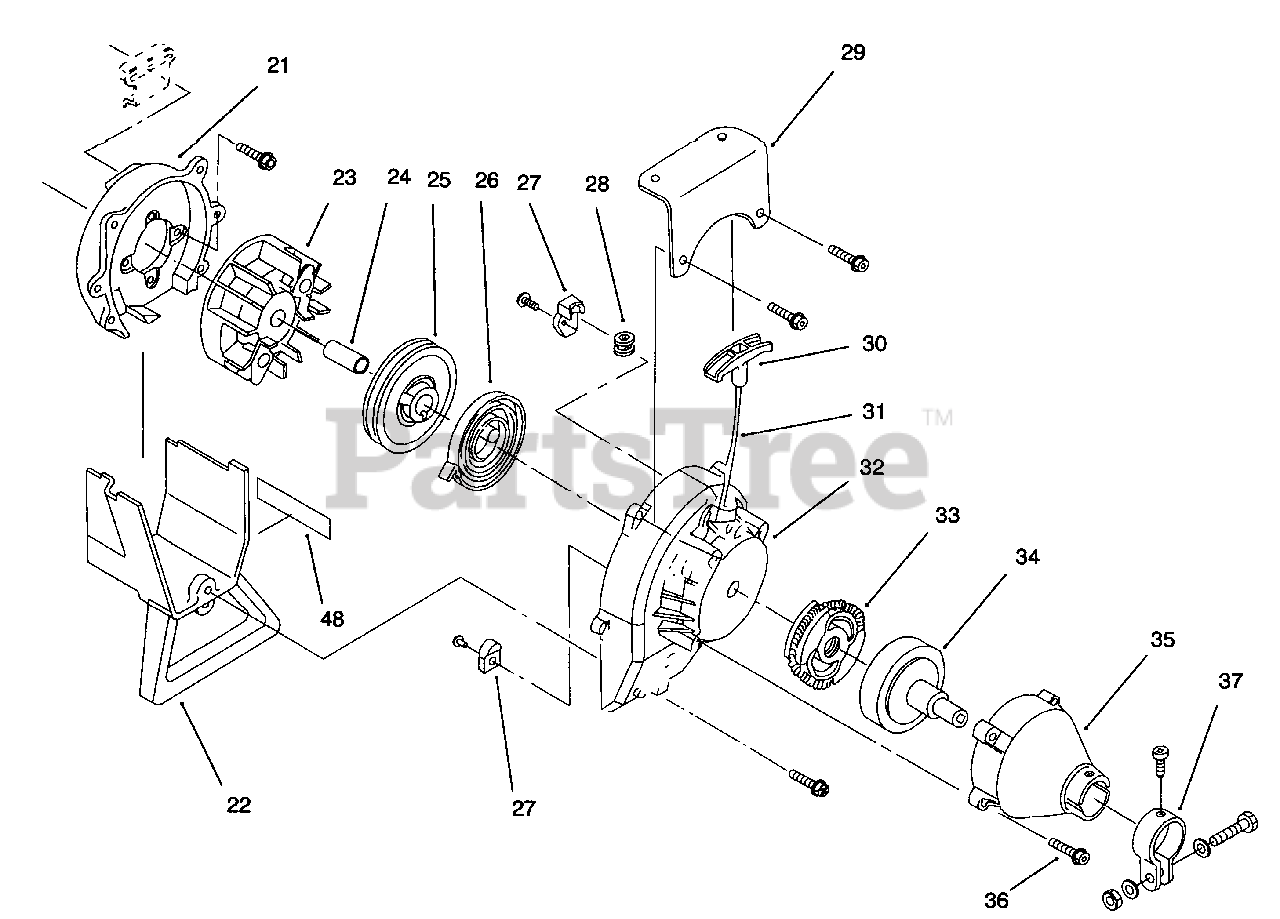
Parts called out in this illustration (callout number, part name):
21	Shroud Asm
22	Shroud Extension & Stand
23	Flywheel Asm.
25	Recoil Pulley Asm.
26	Recoil Spring
27	Pulley Retainer Asm.
28	Rope Guide
29	Fuel Tank Guard Asm.
30	Pull Handle
32	Starter Housing Asm.
33	Clutch Rotor Asm.
34	Clutch Drum Asm.
35	Clutch Cover Asm.
36	Clutch Cover Screw Asm.
37	Upper Clamp Asm.
48	Decal-Warning
